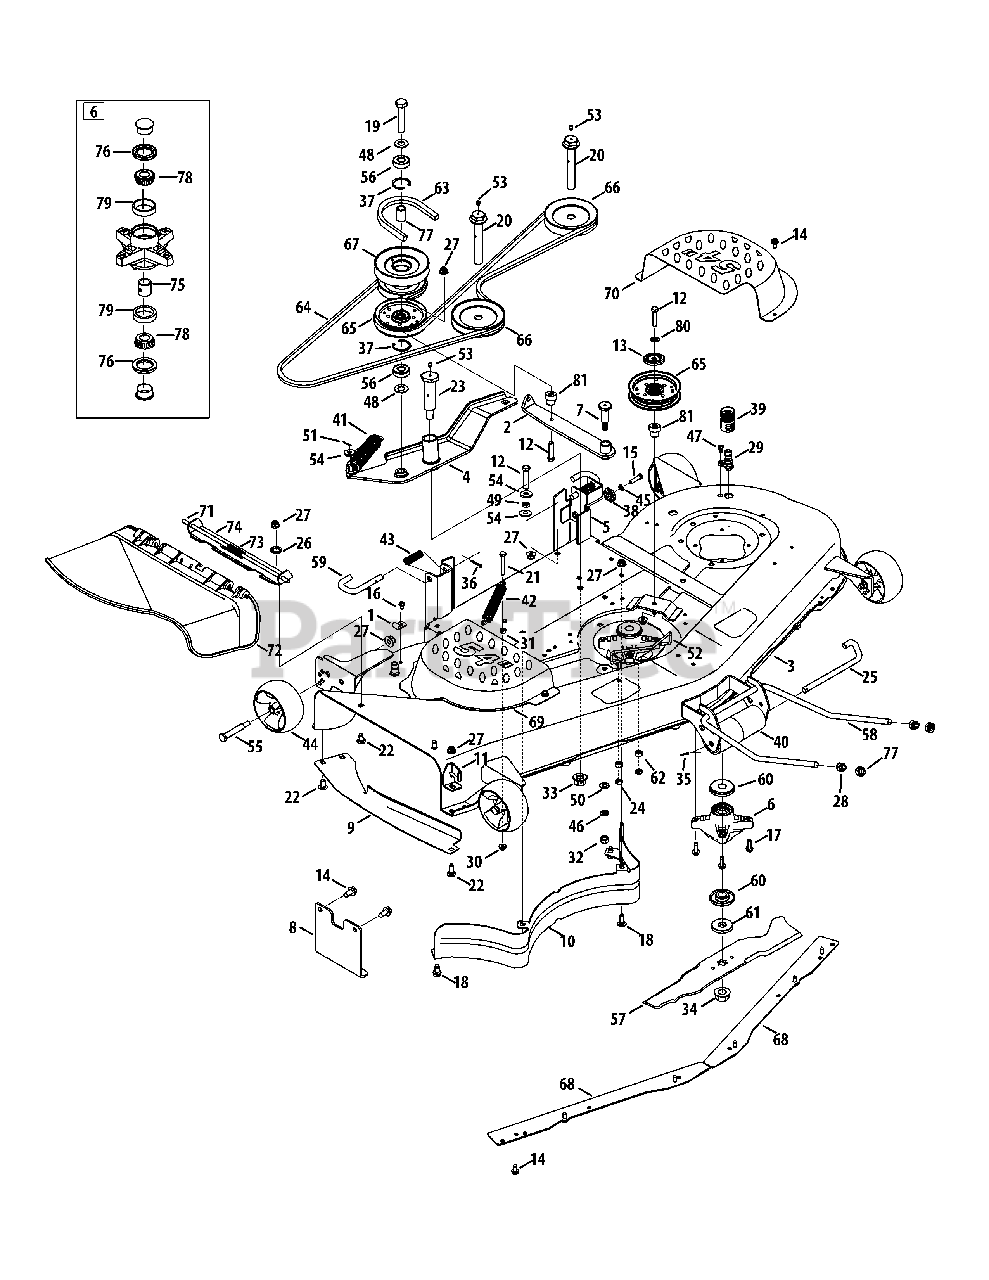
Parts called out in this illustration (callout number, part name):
1	Hook Retainer Bracket
2	Idler Assembly
5	Hanger Adjustment Bracket
6	Spindle Assembly
7	Shoulder Bolt
8	Up-Stop Bracket
12	Hex Screw, 3/8-16 x :1.75
13	Pulley Cap
14	Hex Washer Screw, 5/16-18 x .750
15	Hex Screw, 5/16-18 x 1.25
16	Hex Washer Screw, 1/4-20 x .500
17	Hex Washer Screw, 5/16-18 x 1.000
18	Hex Washer Screw, 3/8-16 x .750
19	SCREW 5/8-18X3.0 GR5
20	Spindle Bolt, 3/4-16 x 5.215
21	Hex Screw, 5/16-18 x 2.25
22	Carriage Bolt, 3/8-16 x 1.00
23	Shoulder Screw, 1.0 x 3.00
24	Hex Lock Nut, 1/4-20
25	Roller Pin, 1/2 x 7.31
26	Push Nut, 3/8
27	Flange Lock Nut, 3/8-16
28	Hex Nut, 1/2-13
29	Deck Wash Nozzle
30	HEX FLANGE NUT
31	Hex Nut, 5/16-18
32	Hex Nut, 7/16-14
33	Flange Lock Nut, 5/8-18
34	Flange Lock Nut, 3/4-16
35	Cotter Pin, 3/32 x 1.25
36	Cotter Pin, 5/32 x 1.25
37	Retainer Ring
38	Deck Adjustment Gear
39	Water Nozzle Adapter
40	Front Roller
41	Extension Spring, 1.25 x 6.9
42	Extension Spring, 1.0 x 6.42
43	Compression Spring, .66 x 1.8
44	Deck Wheel, 5.0
45	Lock Washer, 5/16
46	Lock Washer, 7/16
47	Shoulder Screw, 1/4-20 x 0.50
48	Flat Washer, .65 x 1.25 x .075
49	Jam Nut, 3/8 x 16
50	Flat Washer, .469 x .875 x .105
51	Cotter Pin, 3/32 x .750
52	Belt Drive Guard
53	Drive Lube Fitting, 3/16
54	Falt Washer, .385 x 1.00 x .135
55	Shoulder Screw, 1/2 x 2.50
56	Ball Bearing, .625 x 40 x 12
57	Blade
58	Front Lift Rod
59	Mower Support Pin
60	DECK SPINDLE SPACER
61	Blade Spacer, 2 x .75 x .31
62	Spacer, .256 x .500 x .240
64	Deck Belt
65	Idler Pulley
66	Spindle Pulley
67	Double Pulley
69	RH Belt Cover
70	LH Belt Cover
71	Hinge Pin, .3175 x 14.06
72	Chute Deflector
73	Torsion Spring, .44 x 2.0
74	Chute Bracket
75	Bearing Spacer, .78 x 1.0 x 1.0425
77	Spacer, .88 x .635 x 1.25
78	Cone Bearing, .750
79	Bearing Cup, .750
80	Flat Washer, .406 x .812 x .051
81	Shoulder Spacer, Idler
82	Nut, Jam, 1/2-13
